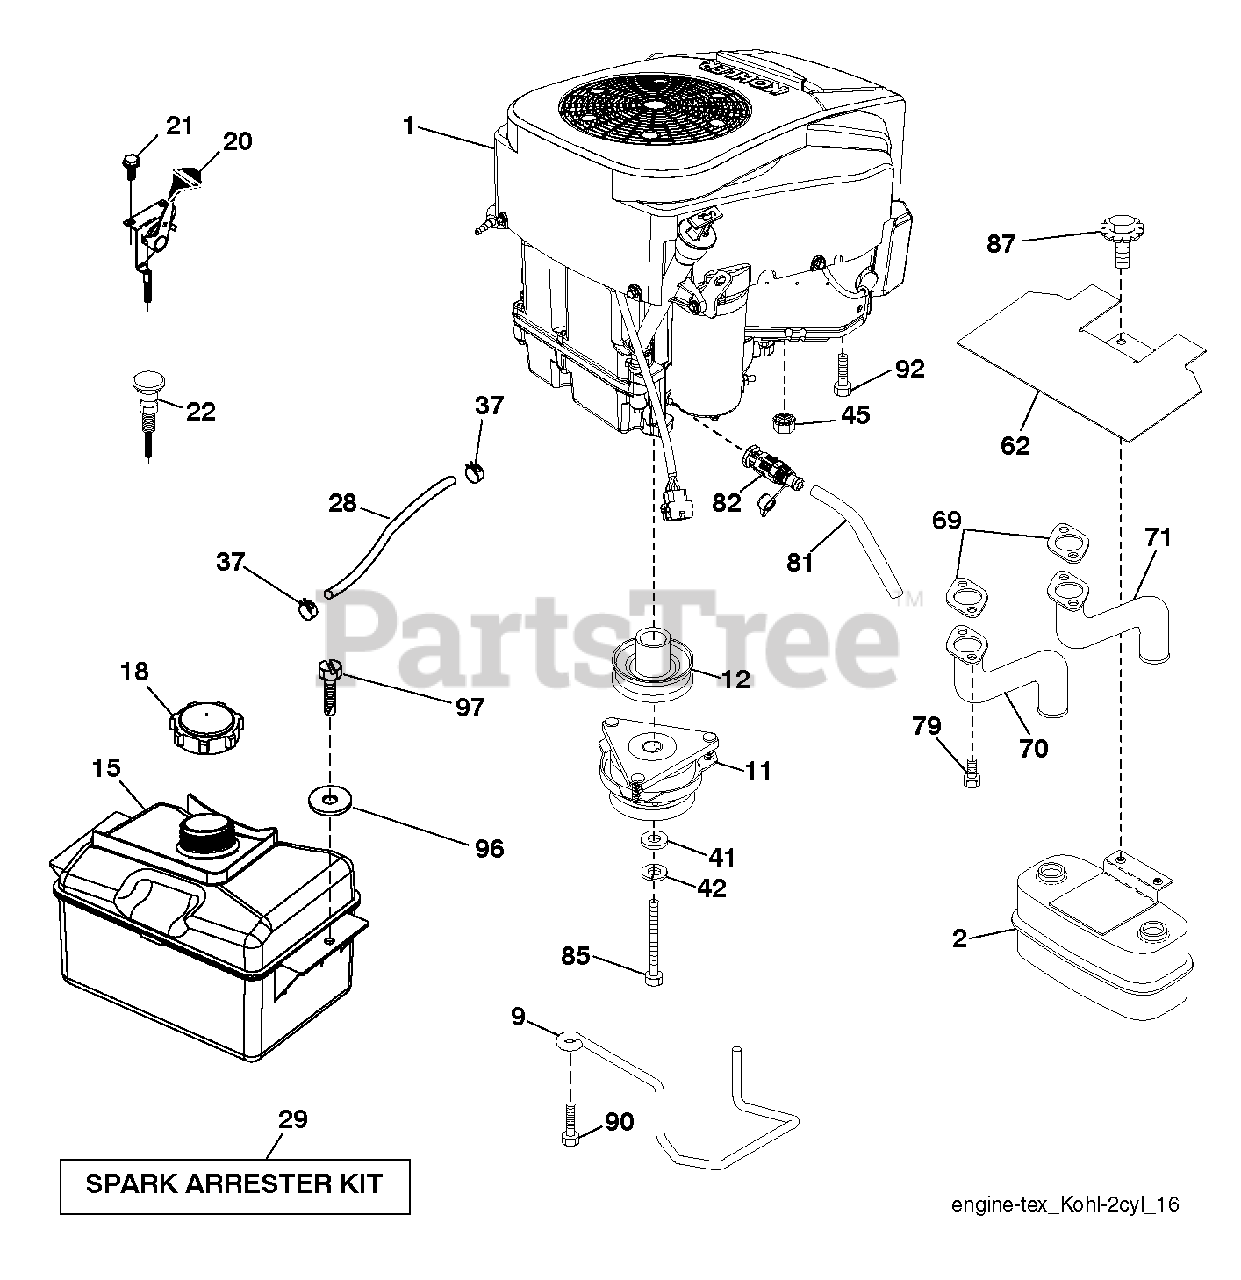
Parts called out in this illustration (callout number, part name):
2	MUFFLER.ASM.TWN.EXTNDED.DFLCTR
9	KEEPER BELT ENGINE
11	CLUTCH.ELECTRIC.LT.48"*
12	PULLEY.ENGINE.TUFFTORQ
15	TANK.ASSEMBL.2.5GAL.NON-EPA
18	CAP ASM.FUEL.2.25"FR.
20	THROTTLE CONTROL
21	SCREW.#10 X 0.750.BOS
22	CONTROL.CHOKE.ERGO.PUSH-IN.BLA
28	LINE.FUEL.64"REAR.EMIS
29	KIT.SPARK ARRESTOR 794945 B&S
37	HOSE CLAMP
42	LOCKWASHER
45	NUT
62	SHIELD.HEAT.MUFFLER
69	GASKET.EXHAUST.KOHL.CV18-CV26
70	PIPE.EXHAUST.LH.CV18/20
71	PIPE.EXHAUST.RH.CV18/20
79	SCREW.SOCKET HD.5/16-1
81	TUBE, DRAIN OIL ASM.
82	VALUE.OIL.DRAIN
85	BOLT HEX 7/16-20X4-1/4"
87	BOLT, 5/16-18 X 1 3/4
90	SCREW 3/8-16X1
92	SCREW 3/8-16X1
97	SCREW HEXWSHR 1/4-20X3/4
